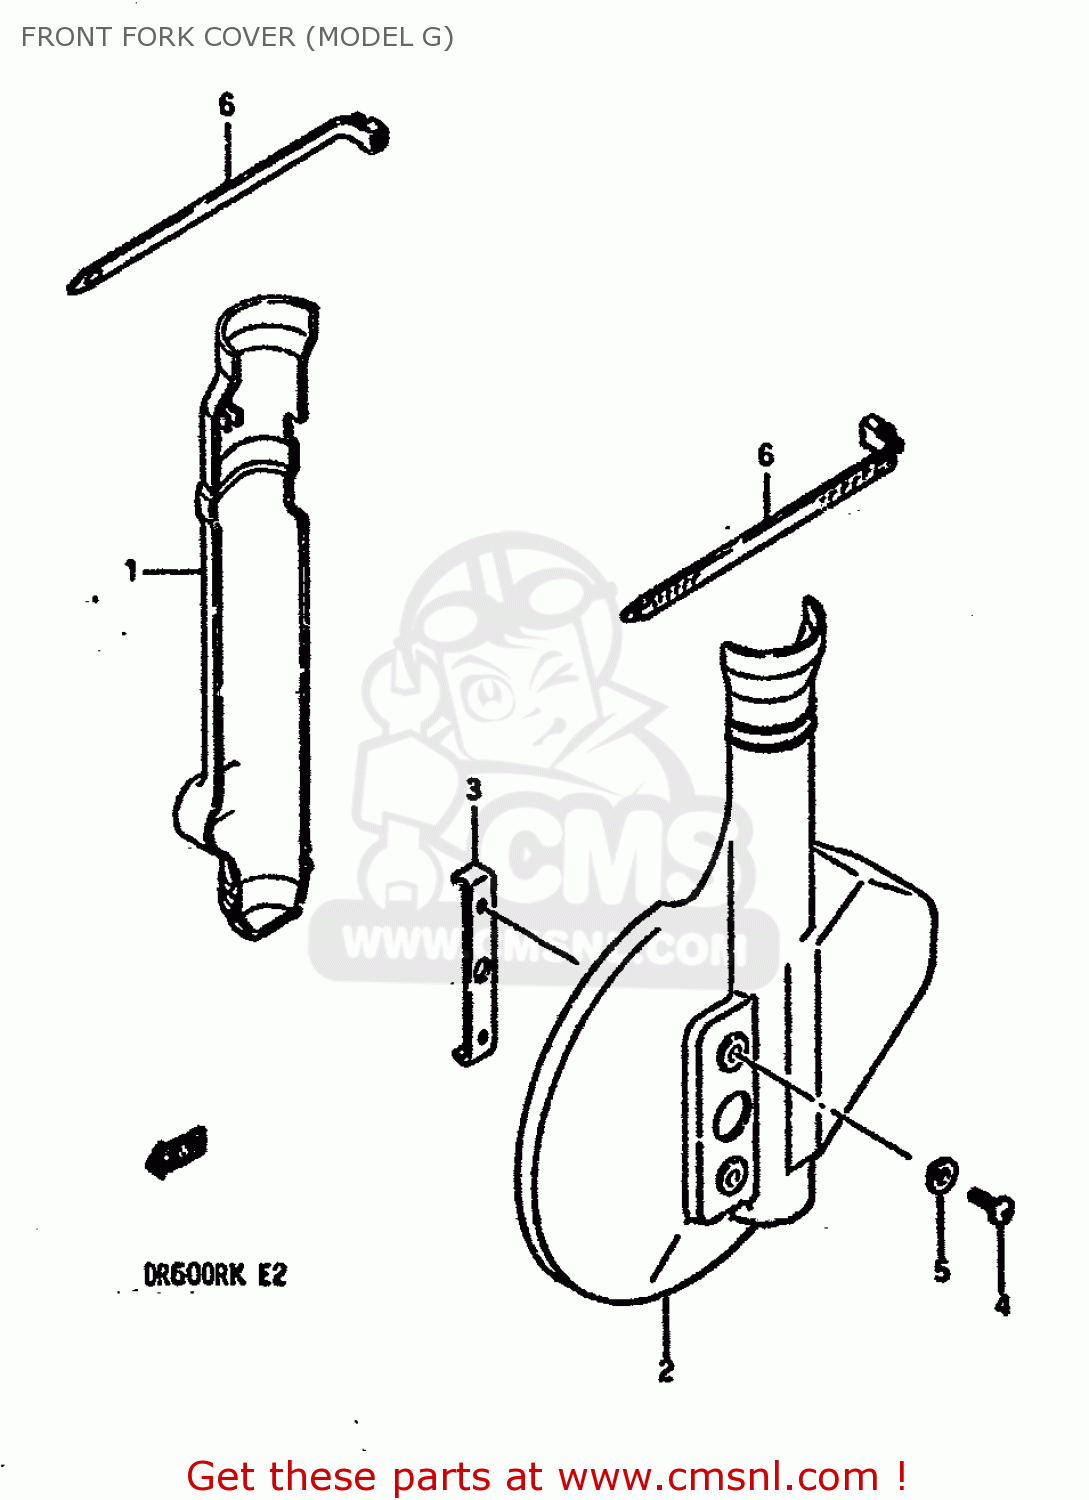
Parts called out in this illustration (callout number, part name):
1	PROTECTOR,FRONT FORK RH
2	PROTECTOR,FRONT FORK LH
3	PLATE, PROTECTOR
4	SCREW 6X12
5	WASHER
6	CLAMP
